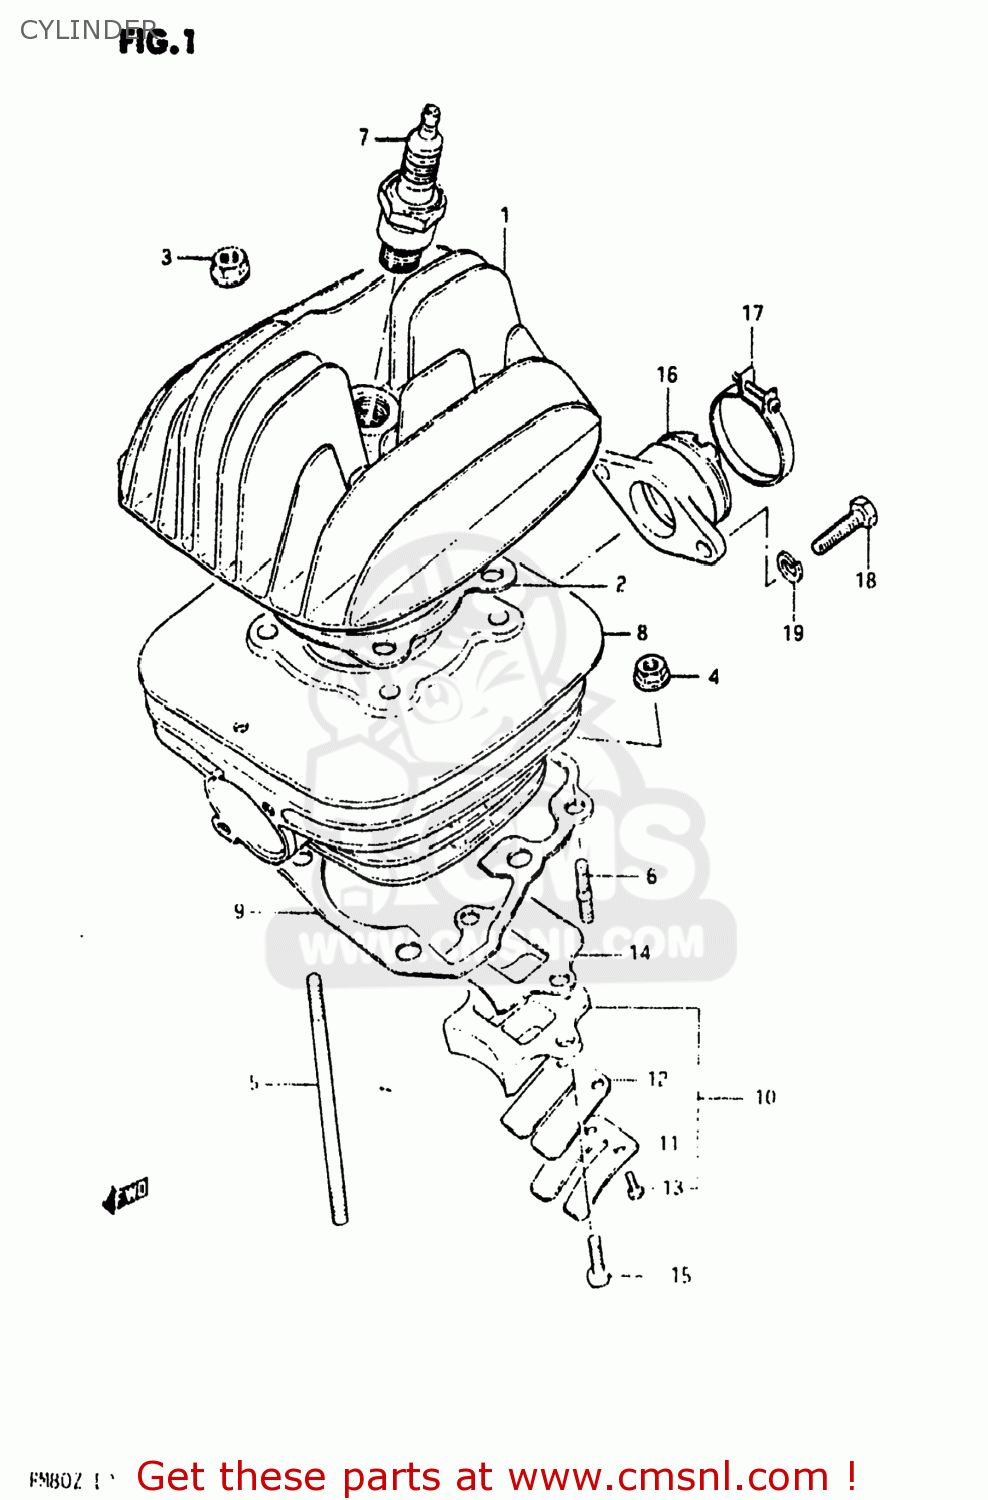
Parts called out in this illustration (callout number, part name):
1	HEAD,CYLINDER
2	GASKET,CYLINDER HEAD (NAS)
3	NUT
4	NUT
5	BOLT,STUD
6	STUD 6X20
7	SPARK PLUG
8	CYLINDER
9	GASKET,CYLINDER (MCA)
10	VALVE ASSY,REED
11	STOPPER,REED VALVE
12	VALVE,REED
13	SCREW,REED VALVE
14	GASKET,REED VALVE (MCA)
15	SCREW
16	PIPE,INTAKE
17	CLAMP
18	BOLT
19	LOCK WASHER
